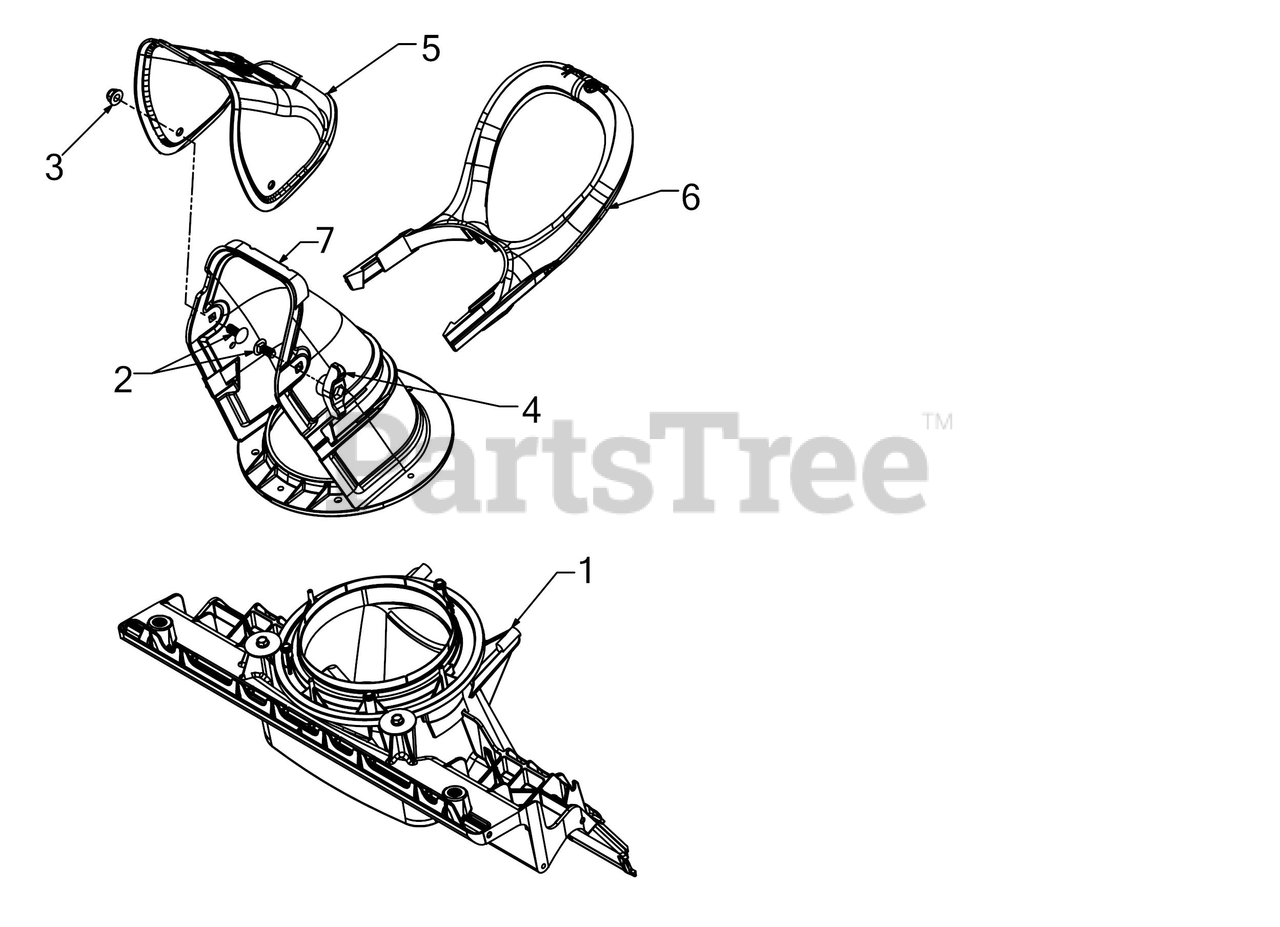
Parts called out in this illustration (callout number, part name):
1	CHUTE ADAPTER ASSEMBLY
2	CARRIAGE BOLT 5/16-18 x .75
3	FLANGE LOCK NUT 5/16-18
4	WING KNOB 5/16-18
5	UPPER CHUTE
6	CHUTE HANDLE
7	LOWER CHUTE 6.5
